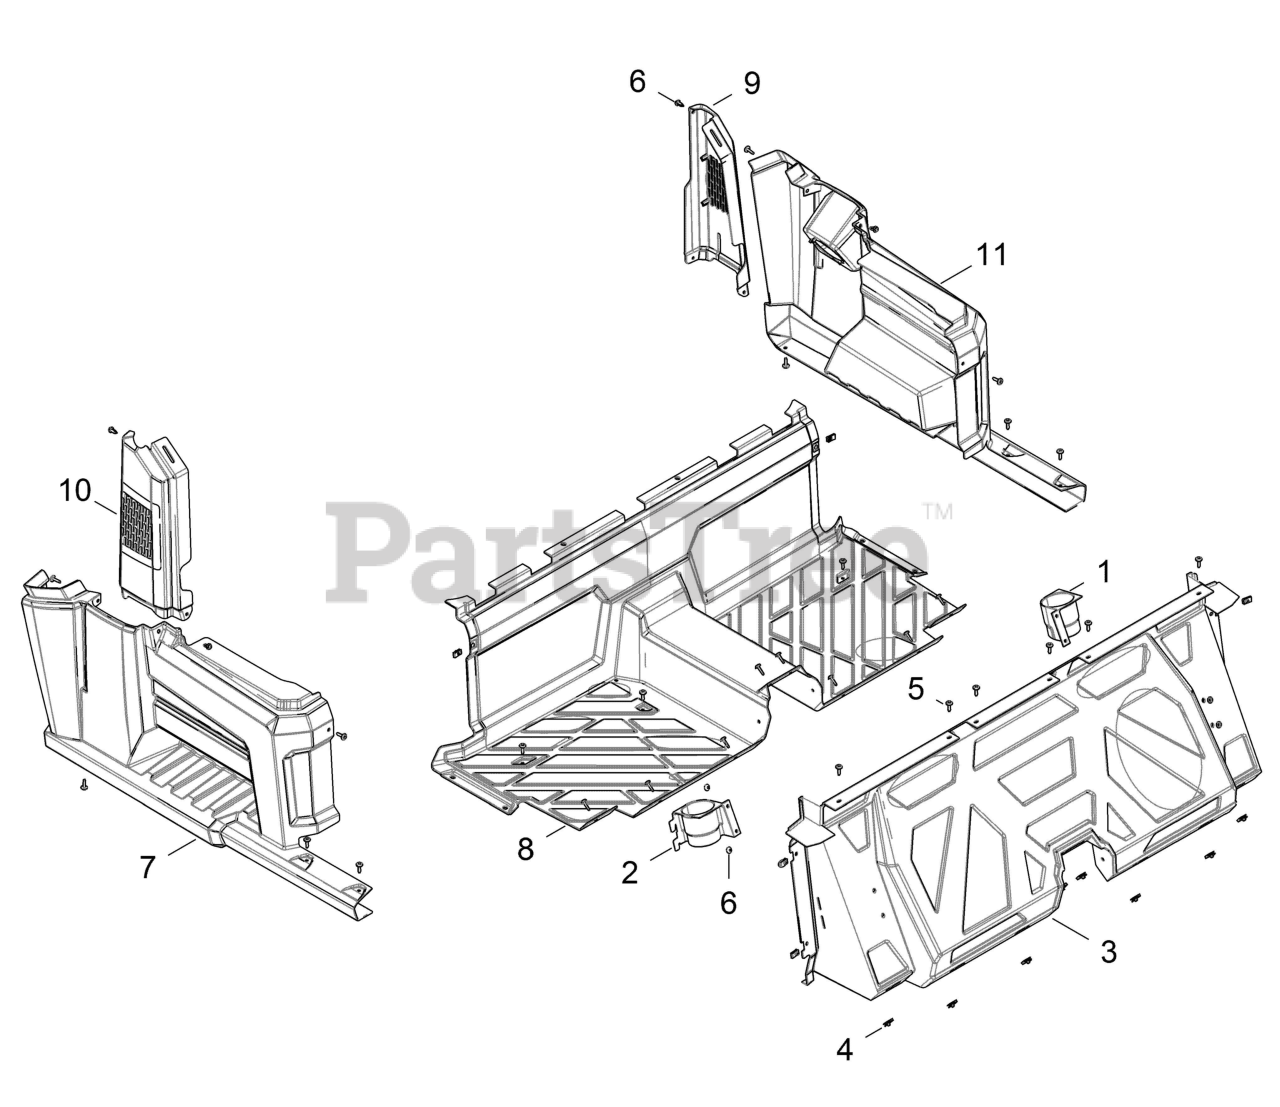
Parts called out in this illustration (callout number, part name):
1	HOLDER, CUP, LH, BLACK
2	HOLDER, CUP, RH,BLK
3	FLOOR,PANEL,REAR,BLK
4	CLIP-U SPEED NUT
5	SCR-TXTH-M6X1.0X25 RIE
6	RIVET-TUFLOK,.315-.325X.787 (5
7	FENDER,REAR,W/ROCKER,CREW,RH
8	FLOOR,REAR,BLK
9	ASM-FENDER-REAR,UPPER,LH,BLK
10	ASM-FENDER-REAR,UPPER,RH,BLK
11	FENDER,REAR,W/ROCKER,CREW, LH
